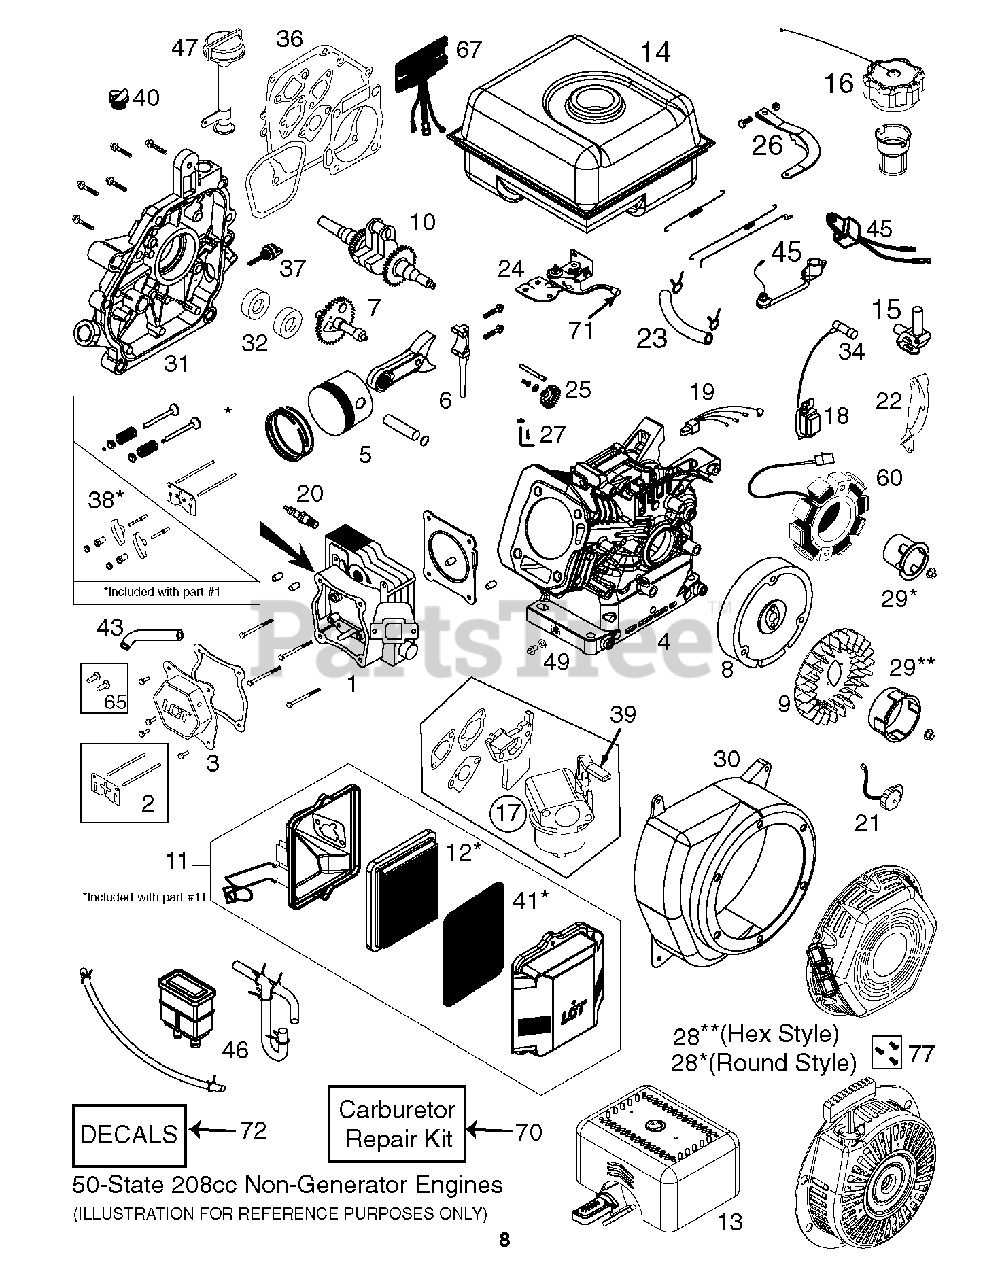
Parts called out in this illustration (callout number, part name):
1	CYLINDR.HEAD.SRV.KIT
2	KIT.PUSH.ROD.SRV(SK208-1001)
3	VALVE COVER ASSEMBLY
4	CYLINDER.GEN2.NO.LOW.OIL.SENSO
5	KIT.PISTON.SRV(SK208-1400)
6	KIT.CONNECT.ROD.SRV(SK208-1500
7	KIT.CAMSHAFT.SRV(SK208-1600)
8	FLYWHL.ASSY.MANUL.SK2081700
9	KIT.COOLNG.FAN.SERV(SK208-4000
10	CRANKSHAFT.KEYED.#14.LCT.208CC
11	FILTER.AIR.ASSEM.CALI.LCT.208C
12	FILTER.ASSEM.PANEL.LCT.208CC
13	50 STATE MUFFLER SERV KIT
14	FUEL.TANK.2.7L.50STATE.LCT.208
15	FUEL.PETCOCK.1/4".LCT
16	CAP.FUEL.50STATE.W/CHAIN.LCT.
17	KIT.CARBURETOR.SERV(SK20-2401)
18	IGNITION.COIL.CDI.STOP.N.CONTR
20	SPARK.PLUG(2083810)
21	KIT.ENGINE.ON/OFF.LCT.208CC
22	SHIELD.FLYWHEEL.GEN2.LCT.208CC
23	FUEL HOSE KIT
24	CONTROL.THROTTLE.S-N-C.LCT.
25	GOVENOR.GEARS ASM(SK2082900)
26	KIT.GOVERNOR.ARM(SUMMER ENG)
27	KIT.GOVERNOR.CRANK(SK208-3100)
28	RECOIL.STARTER.ROUND.BLACK
29	START.CUP.NON-SLOTTED
30	HOUSING.BLOWER.BLACK.LCT.208CC
31	COVER.CRANKCASE.LCT.HIGH.OIL.F
32	SEAL KIT (2 PCS)
34	SPARK.PLUG.BOOT(SK2083800)
36	GASKET.KIT.208CC(SK2084300.1)
37	DIPSTICK SMALL
38	ROCKER ARM KIT
39	CHOKE LEVER.CARB.LCT.208CC
40	NON REMOVABLE PLUG
41	FOAM.PRE.FILTER.LCT.208CC
43	TUBE.BREATHER.LCT.208
46	CARBON.CAN.KIT.LCT(SK2089004)
49	KIT.OIL.DRAIN.PLUG(SK2089911
65	TAPPET.KIT.LCT.208CC
70	CARB.REPAIR.KIT.LCT.SK9900.1
71	KNOB.SPEED.CONTROL.RED.LCT.
77	BOLT.KIT.RECOIL.LCT.ALL.ENGINE
